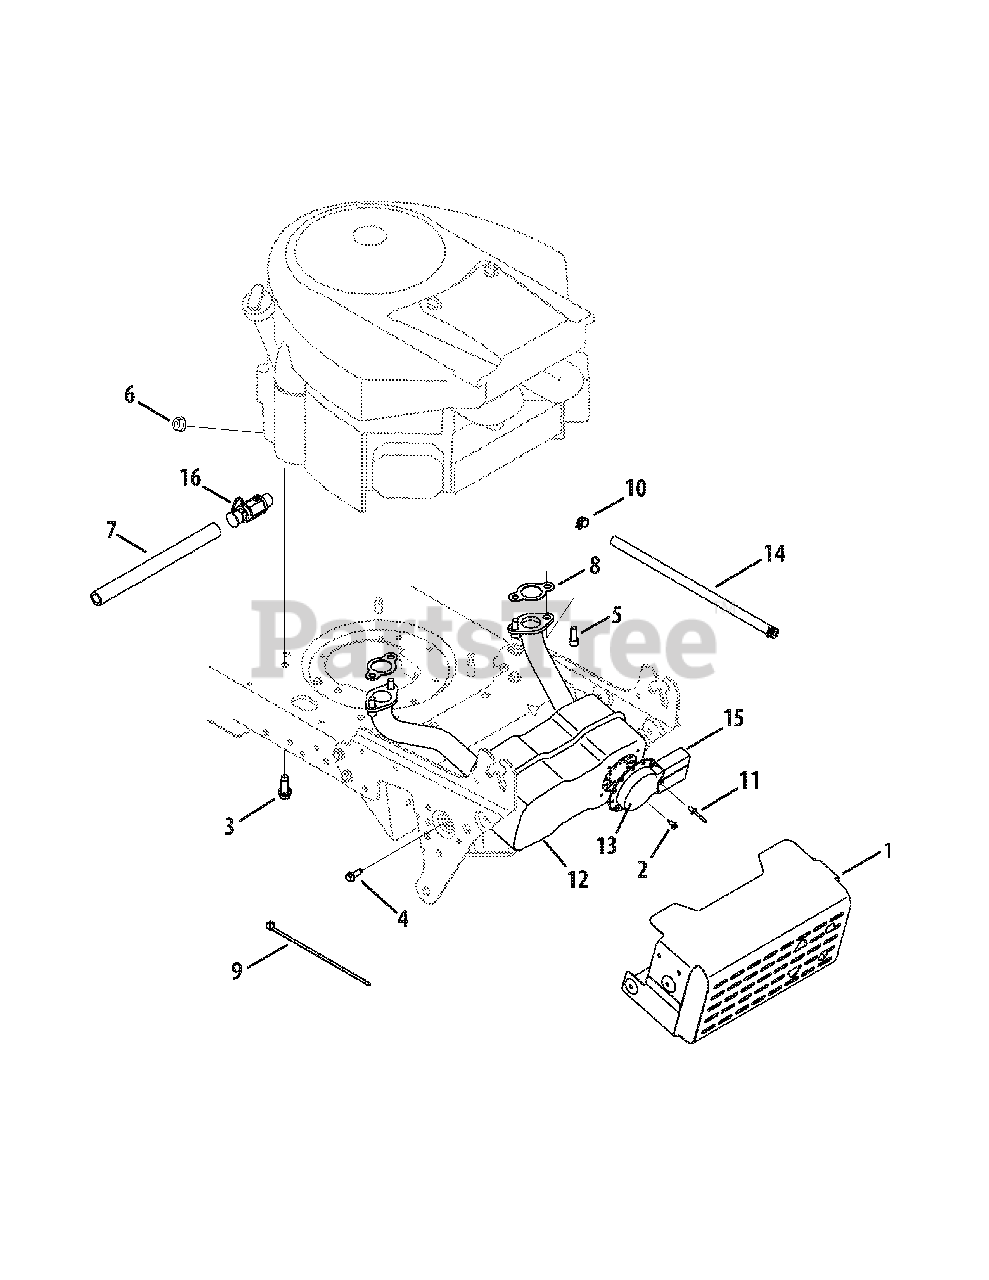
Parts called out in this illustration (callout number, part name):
1	Muffler Assembly Shield
2	AB Screw #8-18 x 0.5
3	TT Screw 3/8-16 x 1.00
4	TT Screw 1/4-20 x 0.750
5	Screw, 5/16-18 x .750
6	Sems Nut, 1/4-20
7	OIl Drain Extension Hose
8	Exhaust Gasket
9	Cable Tie
10	Hose Clamp
11	Pop Rivets, .188 x .300
12	Twin Inlet Muffler
13	Muffler Deflector
14	Fuel Line Hose
15	Long Muffler Deflector
16	Oil Drain Valve
